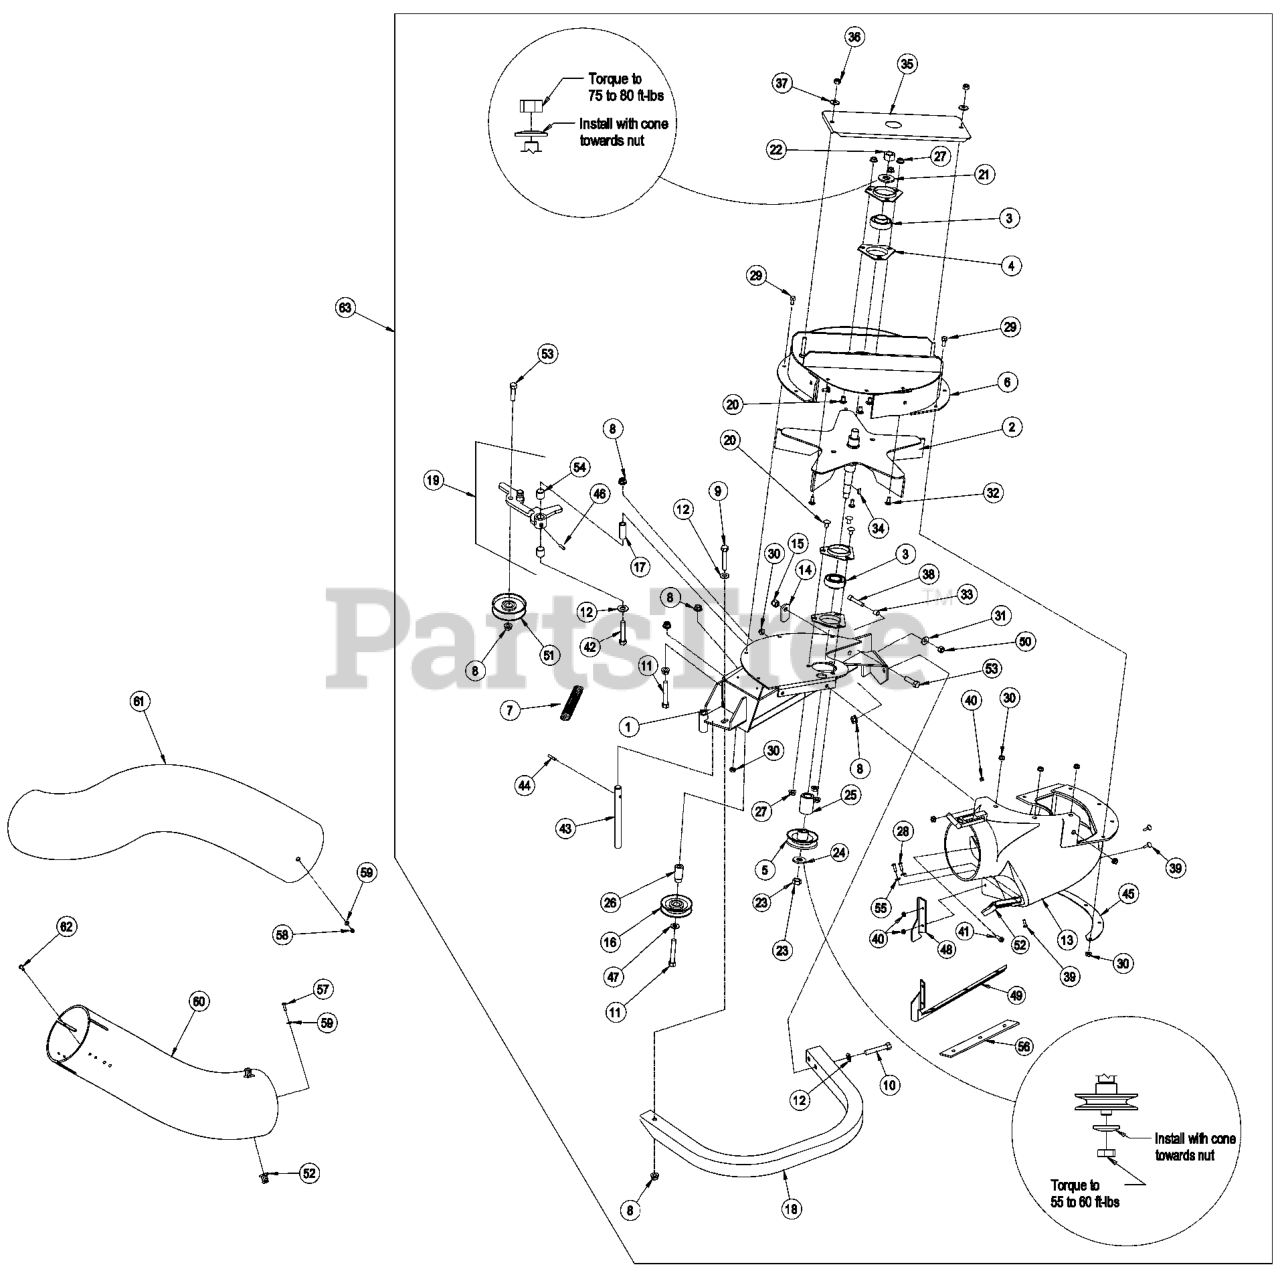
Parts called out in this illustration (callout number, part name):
1	WLD,BLOWER MOUNT
2	IMPELLER
3	BEARING
4	HOUSING-FLANGE
5	SHEAVE-BLOWER
6	ASM, UPPER HOUSING LZUV52
7	SPRING-IDLER
8	NUT-HHF, WHIZ
9	SCREW-HH
10	SCREW-HH
11	BOLT-CARR
12	WASHER-FLAT
13	CHUTE-BLOWER, SMALL
14	LATCH-CATCHER, GRASS
15	NUT-LOCK, NI
16	IDLER-INSIDE
17	BUSHING-PIVOT, IDLER
19	ASM, IDLER ARM - SERVICE
20	SCREW-CARR
21	WASHER-SPRING
22	NUT-HEX
23	NUT-JAM
24	WASHER-SPRING
28	SCREW-PPH
29	SCREW-HH
31	WASHER-SPRING
32	SCREW-CARR
33	BUSHING, LOCATOR
34	KEY-WOODRUFF
35	ASM, BEARING COVER
36	NUT-LOCK, NI
37	WASHER-FLAT
38	SCREW-HSH
39	SCREW-HEAD, TRUSS
42	SCREW-HSBH
43	SHAFT-CATCHER, GRASS
44	PIN-ROLL
45	PLATE-BACKING, BLOWER
46	FITTING-GREASE
47	WASHER-FLAT
48	PLATE, FILLER
49	PLATE, BLOCKER
50	NUT-HEX
51	IDLER-FLAT
52	LATCH DRAW
53	SCREW-HH
54	BUSHING
55	WASHER-FLAT
56	PLATE-REINFORCEMENT
57	SCREW-PPH
58	NUT-LOCK, NI
59	WASHER-FLAT
60	KIT,LOWER TUBE
61	TUBE-UPPER
62	SCREW-HWH
63	ASM, BLOWER LZUV52 - SERV
